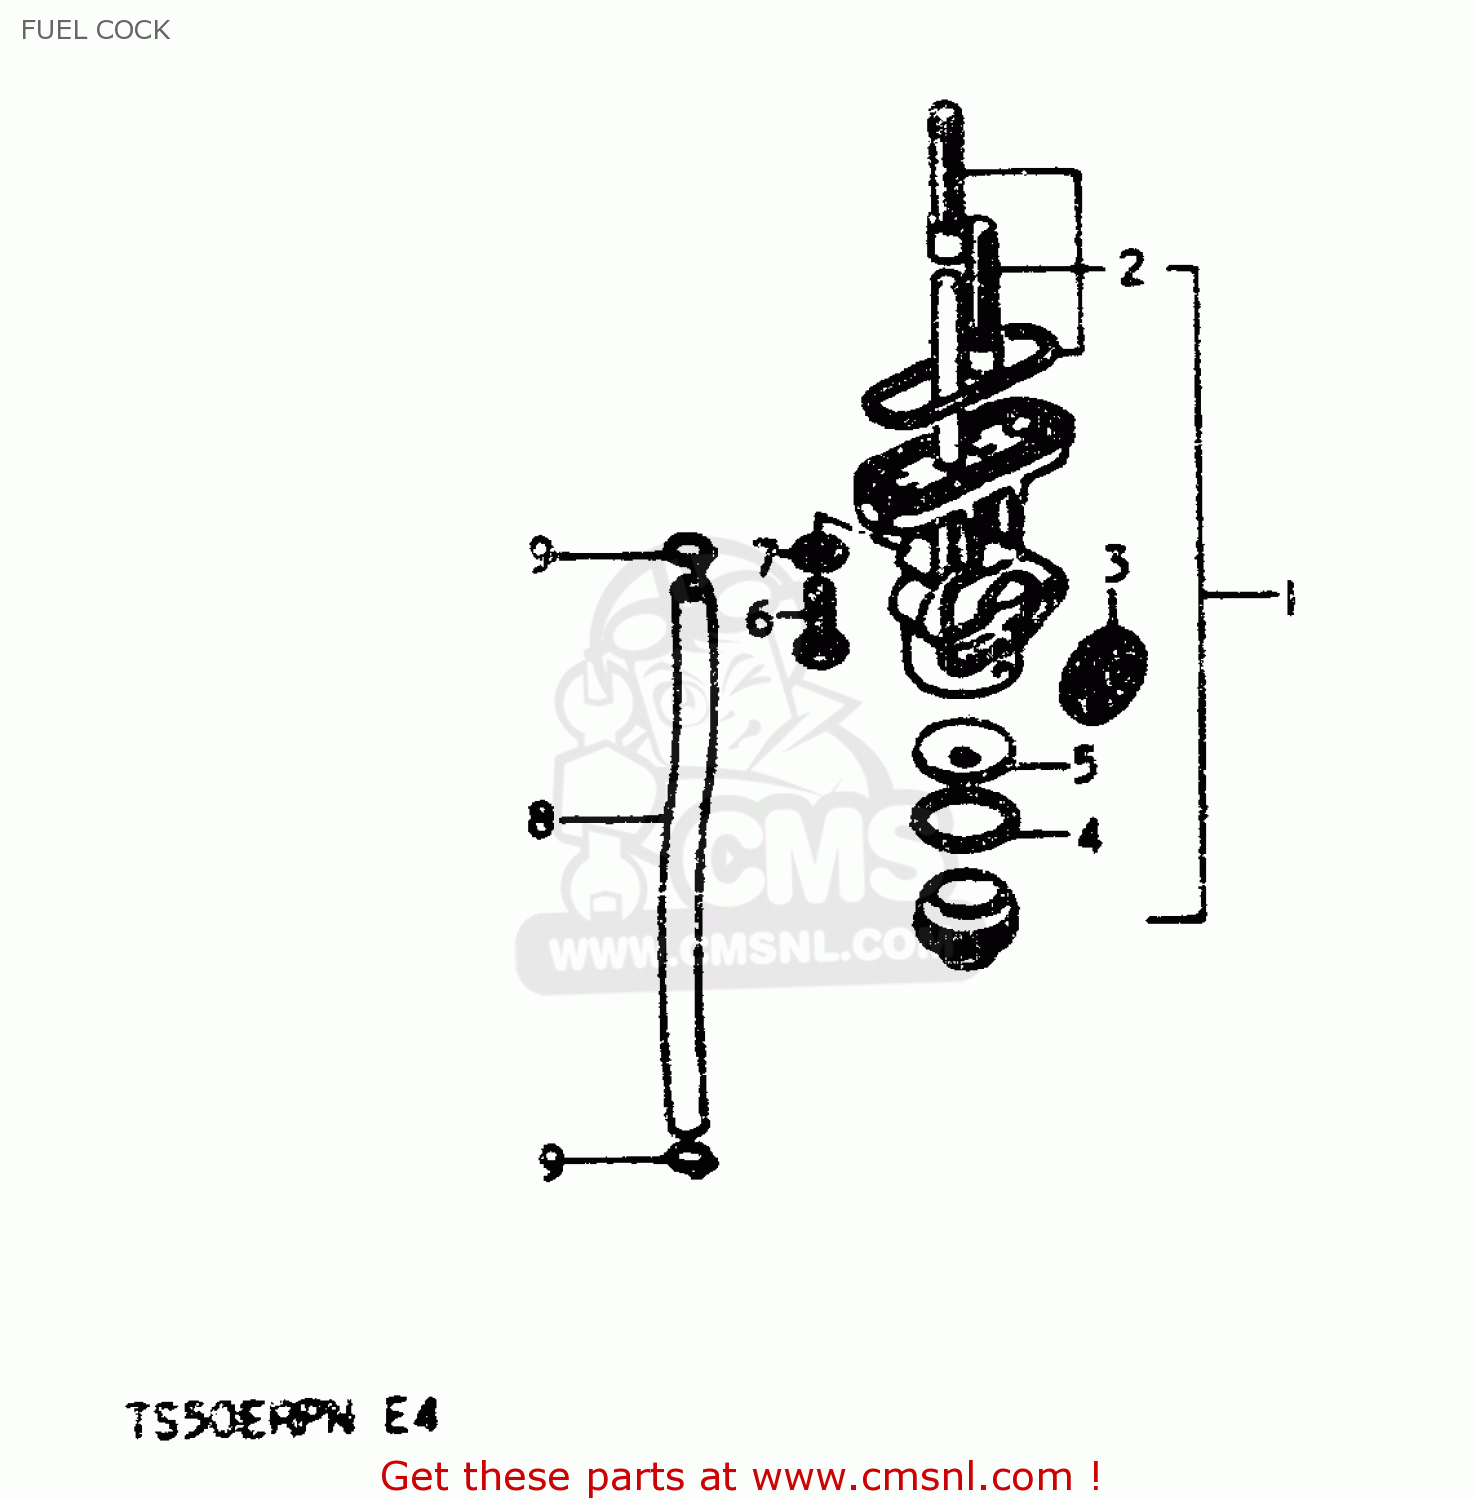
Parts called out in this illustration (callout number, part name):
1	COCK ASSEMBLY,FUEL
2	FILTER SET,FUEL COCK
3	GASKET,LEVER (NAS)
4	GASKET,FILTER (NAS)
5	NET,STRAINER
6	BOLT L:16
7	GASKET
8	HOSE
9	CLIP
